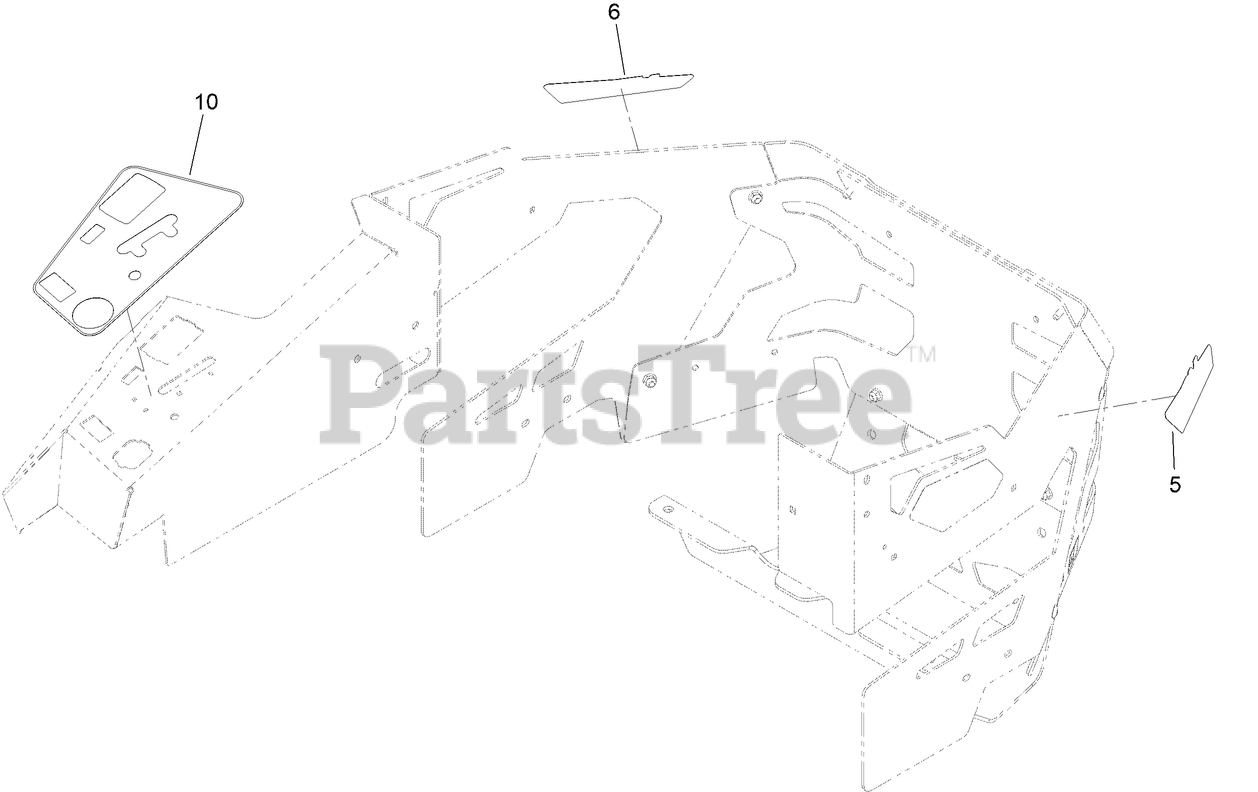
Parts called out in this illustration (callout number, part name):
5	DECAL - HDX
6	DECAL - HDX
10	DECAL-PANEL, CONTROL
